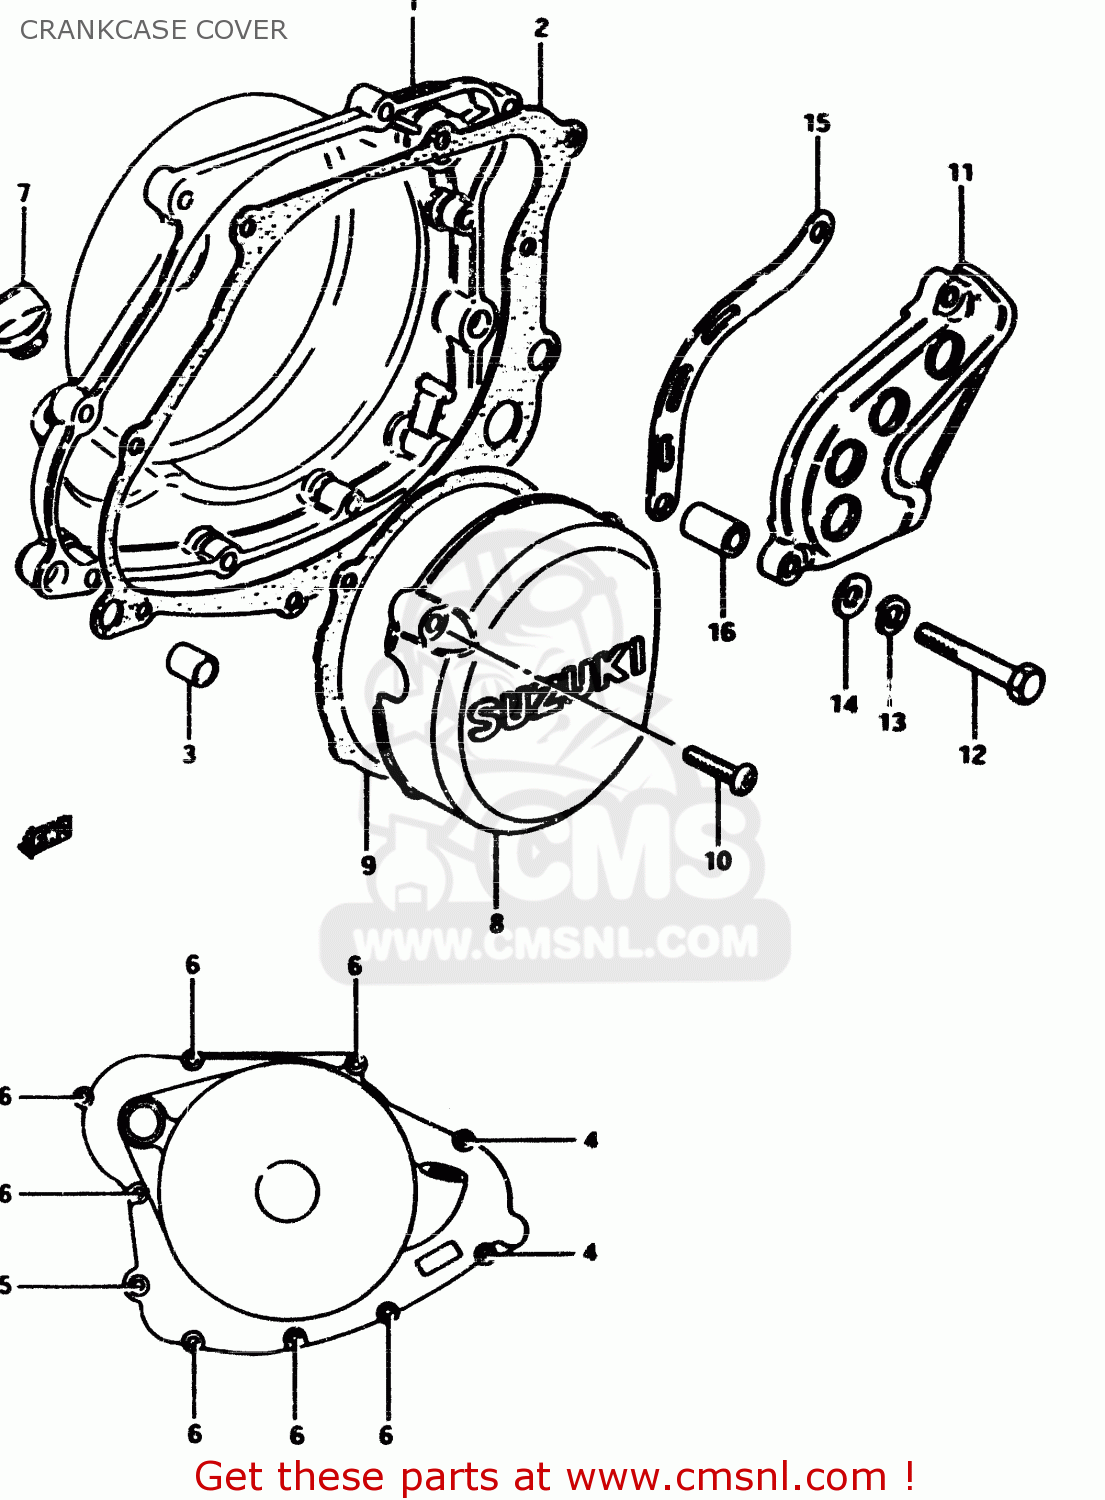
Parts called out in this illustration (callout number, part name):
1	COVER, CLUTCH
2	GASKET,CLUTCH COVER (MCA)
3	PIN
4	SCREW
5	SCREW
6	SCREW
7	PLUG SET
8	COVER,MAGNETO
9	GASKET,MAGNETO COVER (MCA)
10	SCREW
11	COVER, ENGINE SPROCKET
12	BOLT 8X55
13	WASHER,LOCK,8.
14	WASHER
15	PLATE,FR CHAIN GUIDE
16	SPACER(8.6X16X24)
